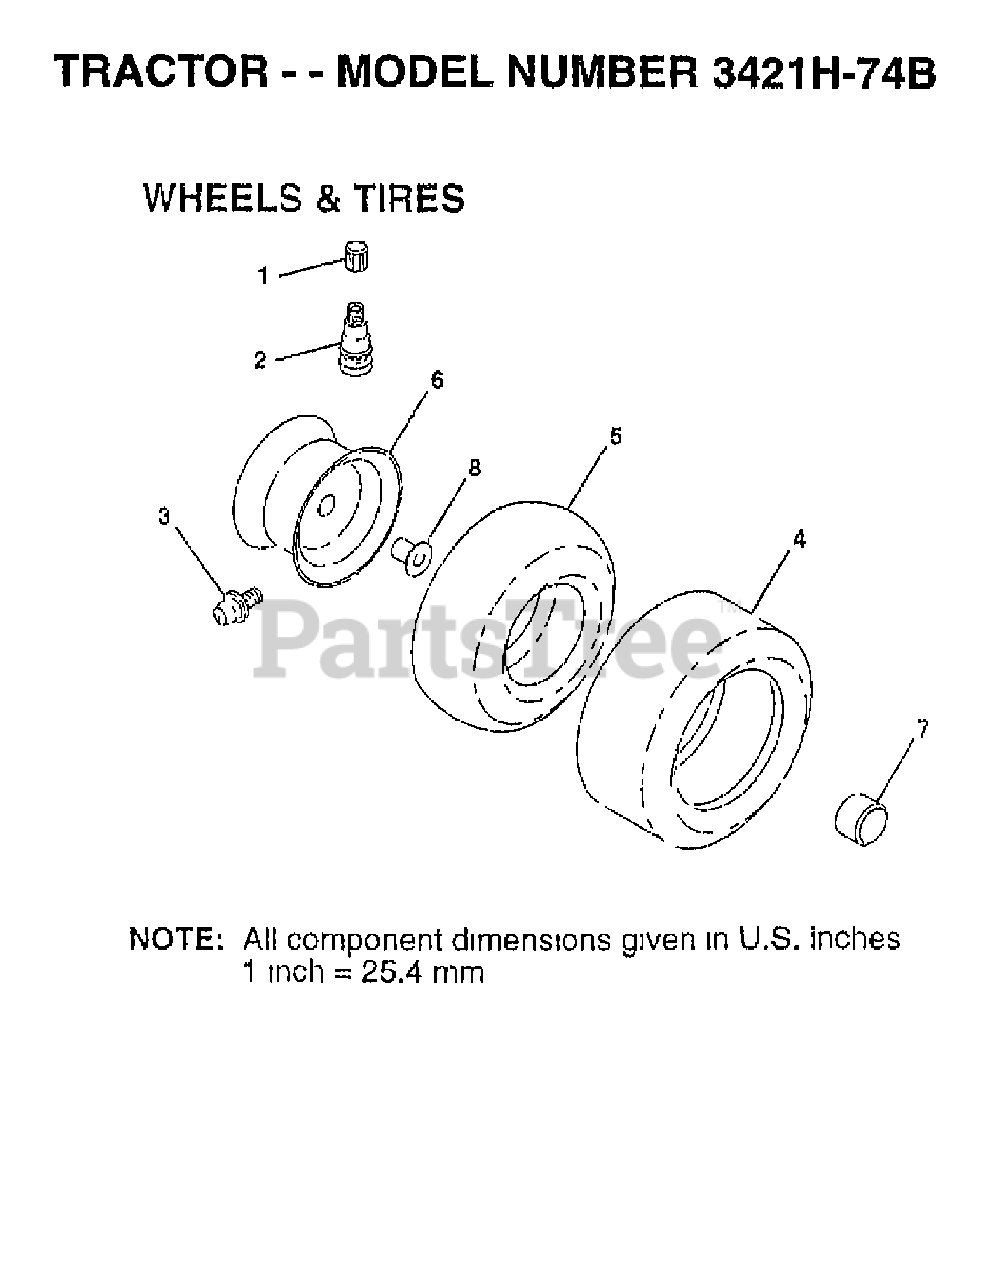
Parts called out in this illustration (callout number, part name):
1	VALVE CAP
2	VALVE STEM LT
3	FITTING LT
4	TIRE HEAVY DUTY
4A	TIRE 20X8-8 TURF SAVER
5	TUBE.5.3/4.5/6
5A	TUBE - UNIVERSAL FOR 8" RIM
6	RIM.ASM.6".FRONT.SILVER
6A	RIM 8" SILVER
7	CAP.HUB.FRONT.LT.BLACK
8	BEARING T
